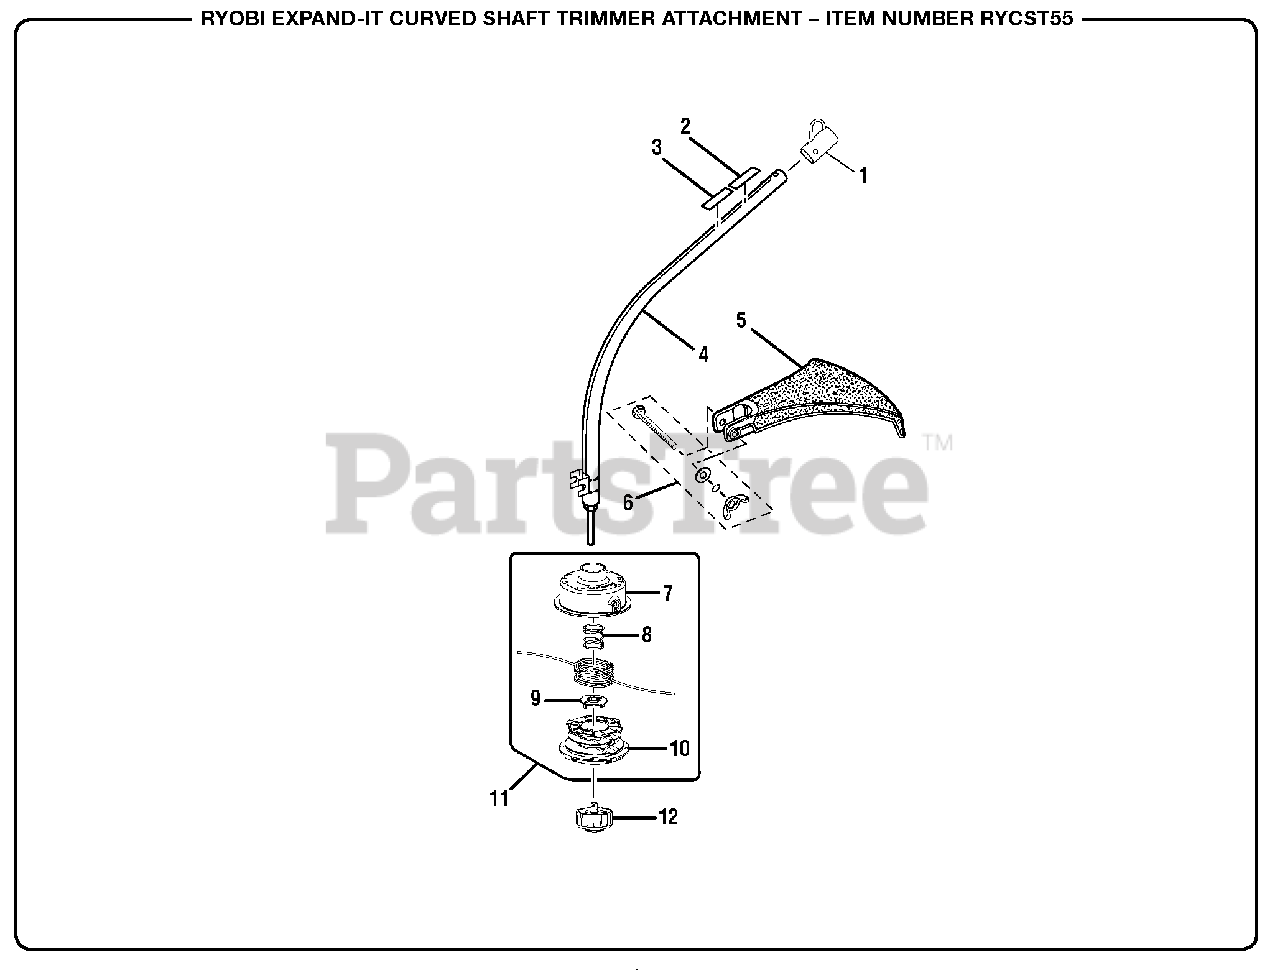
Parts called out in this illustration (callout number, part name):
1	Hanger Cap
2	Warning Icon Label
3	Expand-it Logo Label
4	Curved Shaft Assembly
5	Curved Shaft Grass Deflector
6	Washer and Bolt Assembly
7	String Head Housing
8	Compression Spring
9	String Guide
11	String Head Assembly
12	Spool Retainer
